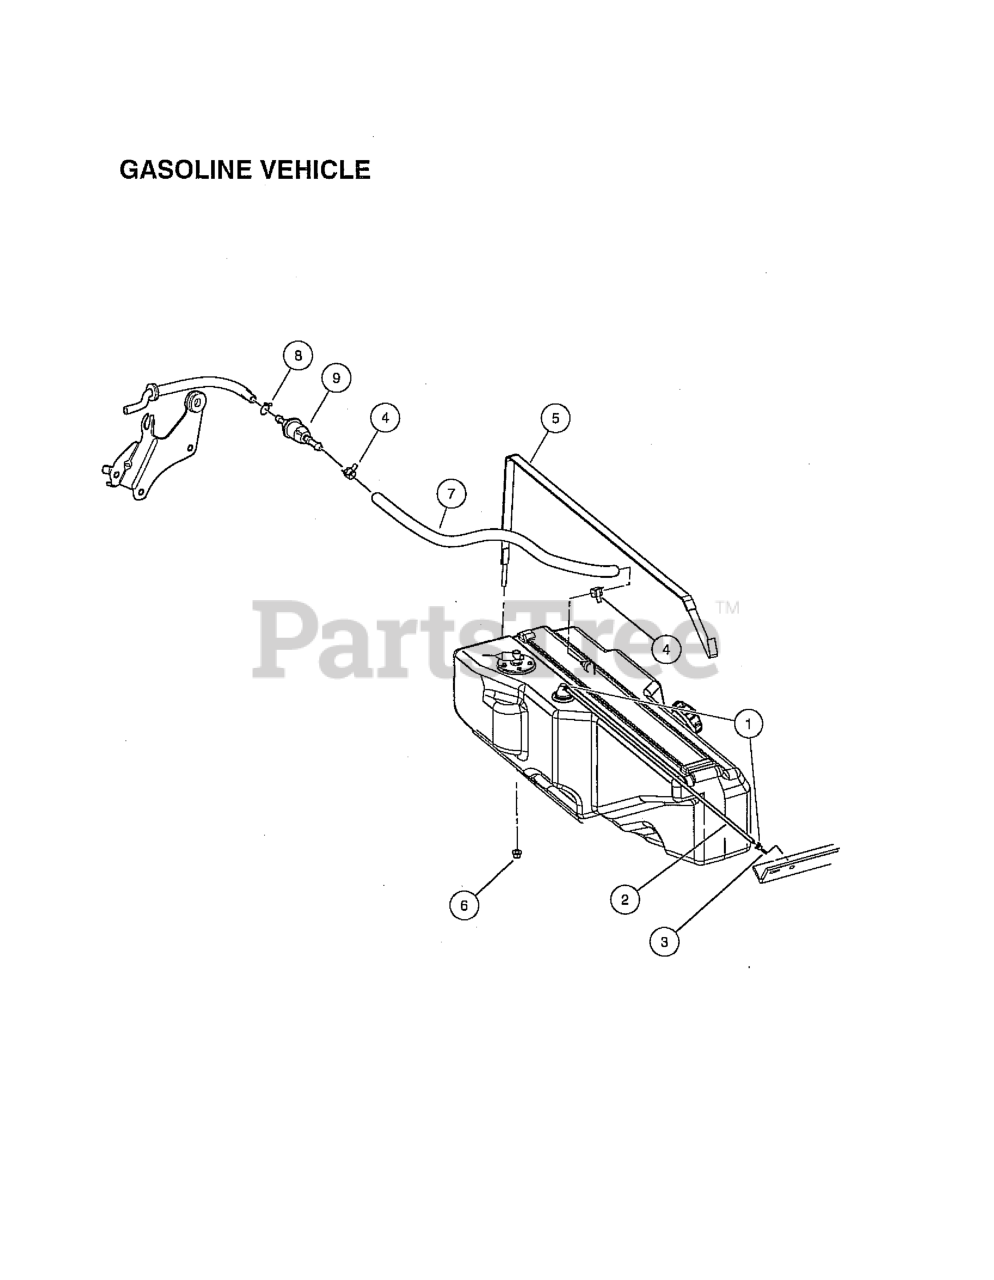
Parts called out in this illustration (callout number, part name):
2	TUBE, CARBURETOR AIR VENT
4	CLAMP, HOSE, CTB 13MM
5	STRAP, TANK, FUEL
6	NUT FLG, M8 X 1.25 MECH DEF
7	HOSE, TANK TO FILTER, GAS
8	CLIP, TUBE, B10
9	FILTER FUEL
